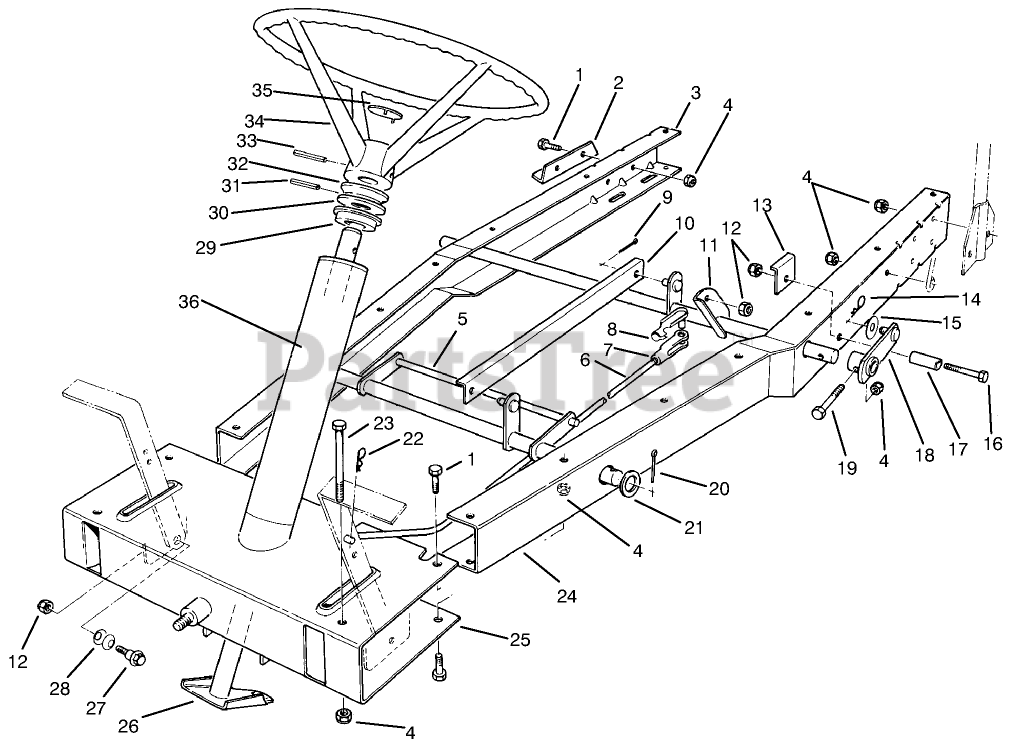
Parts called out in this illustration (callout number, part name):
1	SCREW-HH
2	MOUNT-AXLE BEARING
4	NUT-LOCK, NI
5	FRT DECK LIFT WA
6	ROD-CLUTCH
7	CLEVIS-ADJ
8	Assembly-Pin, Clevis
9	PIN-COTTER
10	LINK-HOC BRACKET
11	TUBE ASM-REAR SUPPORT
12	NUT-LOCK, NI
13	DECK STOP BRACE
14	PIN-HAIR
15	WASHER
16	SCREW-HH
17	SPACER-STOP,DECK
18	HOC LEVER WA
19	AXLE MTG BOLT
20	PIN-COTTER
21	WASHER-FLAT
22	PIN-COTTER
23	SCREW-HH
24	FRAME-CHANNEL LH *
27	BOLT-SHOULDER
28	WASHER-BELLEVILLE
30	WASHER-STEERING
31	PIN-ROLL
32	SPACER-STEERING
33	PIN-ROLL
34	STEERING WHEEL ASM
35	INSERT - STEERING WHEEL, LAWNBOY
36	DECAL - STEERING COLUMN
